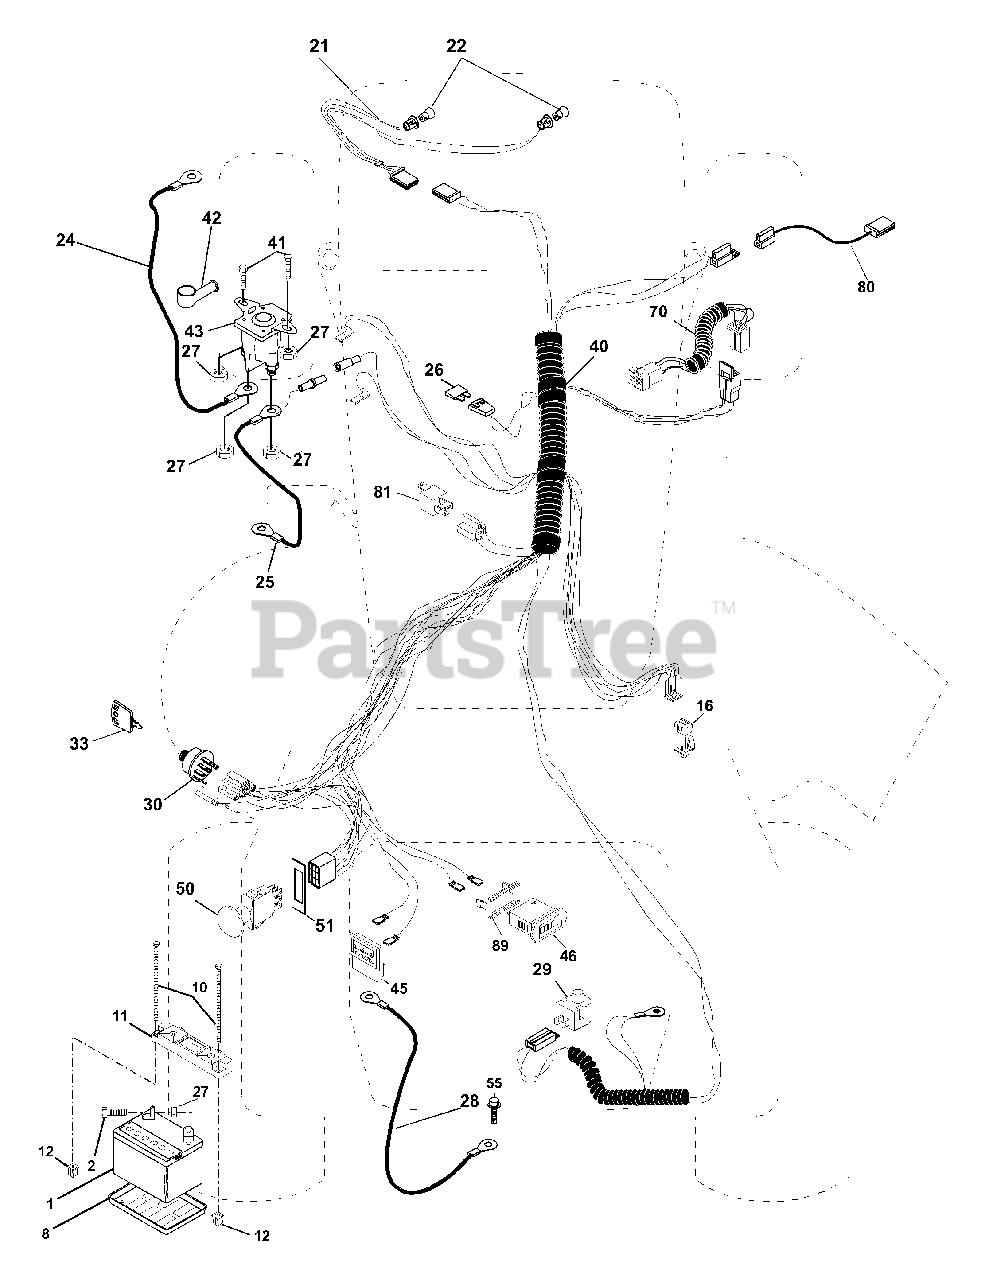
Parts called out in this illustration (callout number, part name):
1	Battery 12 Volt 35 AMP
2	Bolt Hex Hd 1/4-20unc X 3/4
8	Tray Battery
10	Bolt Brt Frt 1/4-20 x 75 Ainc
11	Holddown Battery Front Mount
12	Nut Push Nylon 1/4" Battery Frt
16	Switch Interlock Push-In
20	Nut Jam Hex 1/4-20 Unc
21	Harness Asm Light W/4152j
22	Bulb Light #1156
24	Cable Battery 6 Ga 11" red
25	Cable Battery 6 Ga 22" red w/16 wire
26	Fuse 15 AMP
27	Nut Keps Hex 1/4-20 Unc
28	Cable Ground 6 Ga 21" black
29	Switch Plunger Nc Gray
30	Switch Ign
33	Key Ign Molded Generic
40	Harness Ign.
41	Bolt Blk Fin Hex 1/4 - 20 x 1/2
42	Cover Terminal Red
43	Solenoid
45	Ammeter Rectangular 15 Amp
46	Meter Hour
50	Switch PTO 3 PDT Black Delta
51	Ring Retainer TTO
55	Screw Thdrol 5/16-18 x 1-1/2 Tyt
70	Harness, Eng.
80	Harness Clutch Evx
81	Relay Asm.
89	Bracket Snap-In Hourmeter
